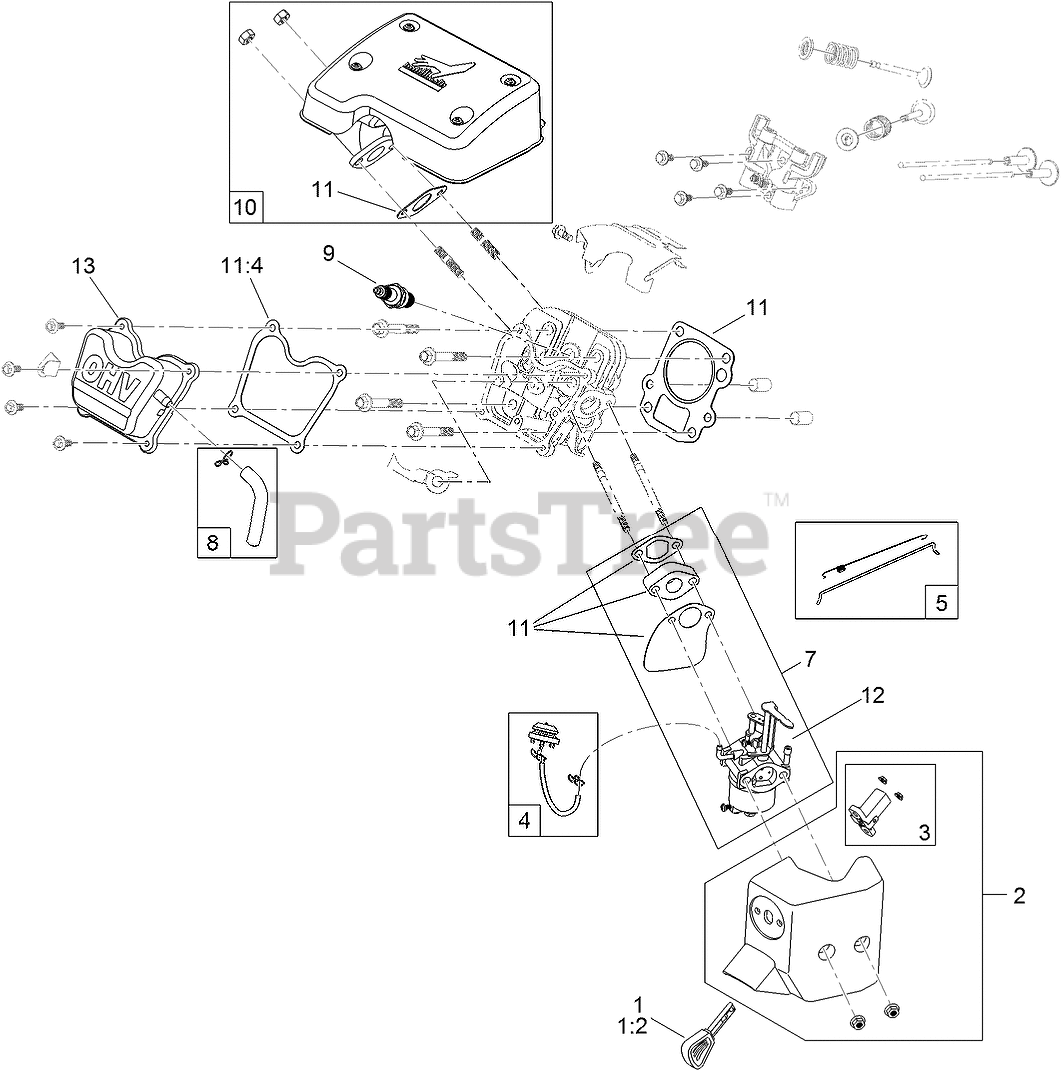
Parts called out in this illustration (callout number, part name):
1	KEY AND LANYARD KIT
2	HEATER BOX KIT
3	SWITCH KIT
4	PRIMER BULB KIT
5	GOVERNOR KIT
7	COMPLETE CARB SERVICE KIT
8	BREATHER TUBE KIT
9	SPARK PLUG
10	MUFFLER KIT
11	GASKET, SEAL AND O-RING KIT
11:4	GASKET-COVER, VALVE
12	CARB FLOAT AND NEEDLE KIT
13	VALVE COVER ASM
